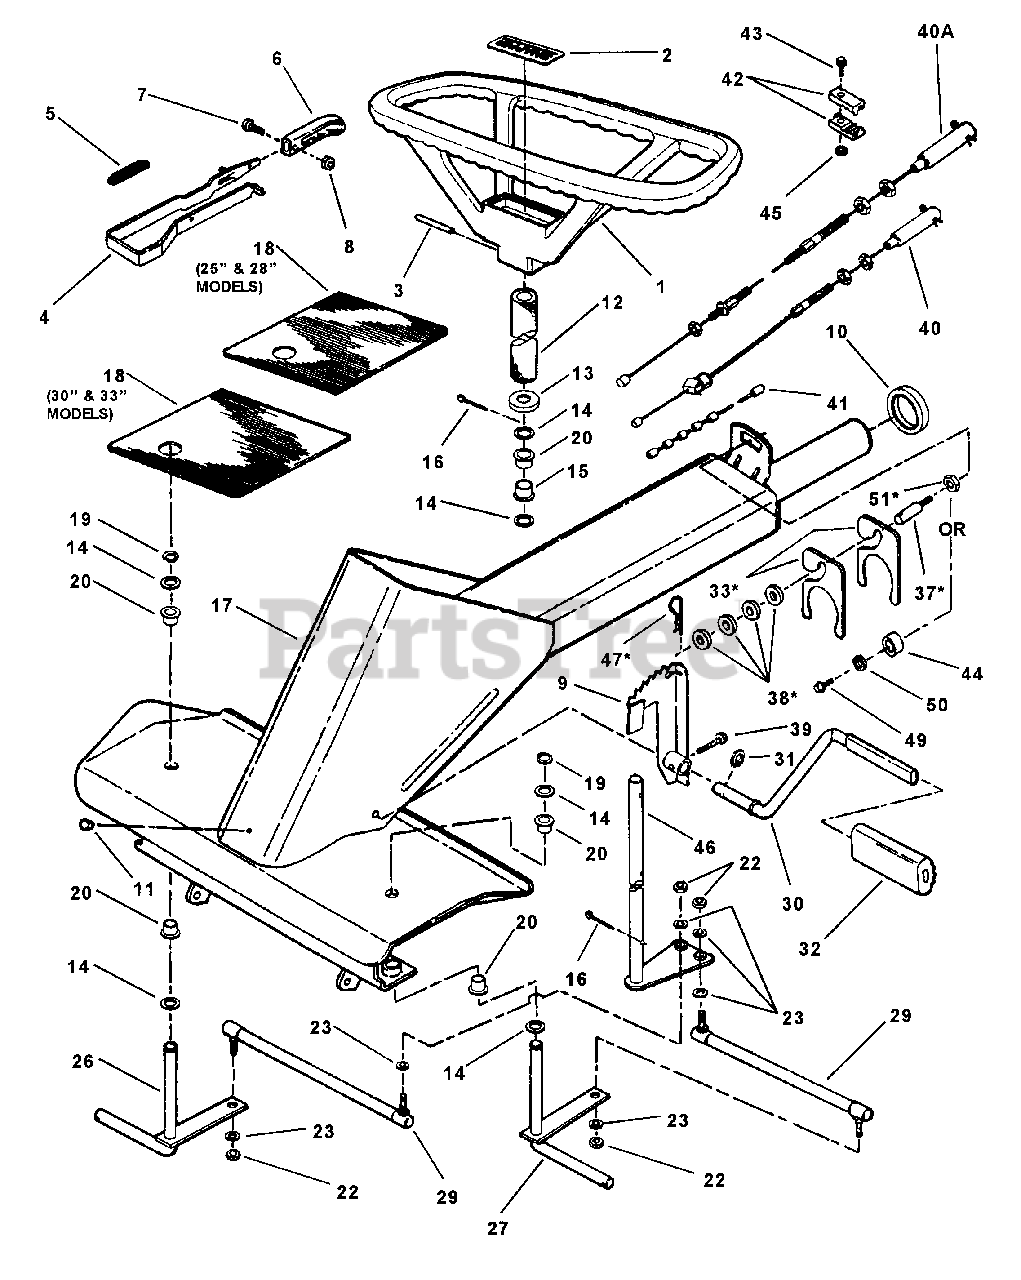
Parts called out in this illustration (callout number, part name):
1	ASSEMBLY, Steering Wheel
2	DECAL, Snapper
3	PIN, 1/4 x 1-1/2" Roll
4	LEVER, Park Brake
5	SPRING
6	KNOB
7	SCREW, #8-32 x 3/8" Cross Recess
8	NUT, #8-32 Hex, Grade 2B
9	ARM, Clutch/Brake (Weldment)
10	SPACER, Main Tube
11	PLUG
12	COVER, Steering Shaft (Foam)
13	COVER, Steering Shaft
14	WASHER, 3/4" Flat
15	BUSHING, 3/4" Steering Shaft
16	COTTER-PIN, 3/16 x 1-1/2"
17	FRAME, Front
18	PAD, Foot (Right Side)
19	RING, 3/4" Retaining
20	BEARING, Nylon
22	NUT, 5/16-24 Hex, Gr. 5
23	WASHER, 5/16" Split Lock
26	PIN, Wide King (Right Side), 11.0" Tires
27	PIN, Wide King (Left Side), 11.0" Tires
29	TIE-ROD
30	PEDAL, Clutch/Brake
31	RING, 5/8" External Retaining
32	PAD, Clutch/Brake Pedal
33	SPACER, Pivot
37	STUD, 3/8-24 x 5/8"
38	SPACER
39	SCREW, 5/16-18 x 1-1/4" Hex Washer Self-Tapping
40	CABLE, Brake (Snap-in)
40A	CABLE, Brake
41	CABLE, Clutch
42	CONNECTOR, Cable
43	SCREW, 1/4-20 x 3/4" Hex Head Cap, Grade 5
44	SPACER, .39 x .625 x .19" Sintered Iron
45	NUT, 1/4-20 Hex Center Lock
46	SHAFT, Steering (Wide Front End)
47	HAIRPIN, 1/8 x 2-9/16"
49	SCREW, 3/8-16 x 5/8" Hex Washer Self-Tap
50	WASHER, 3/8" Flat
51	NUT, 3/8-24 Hex Nyloc Q
